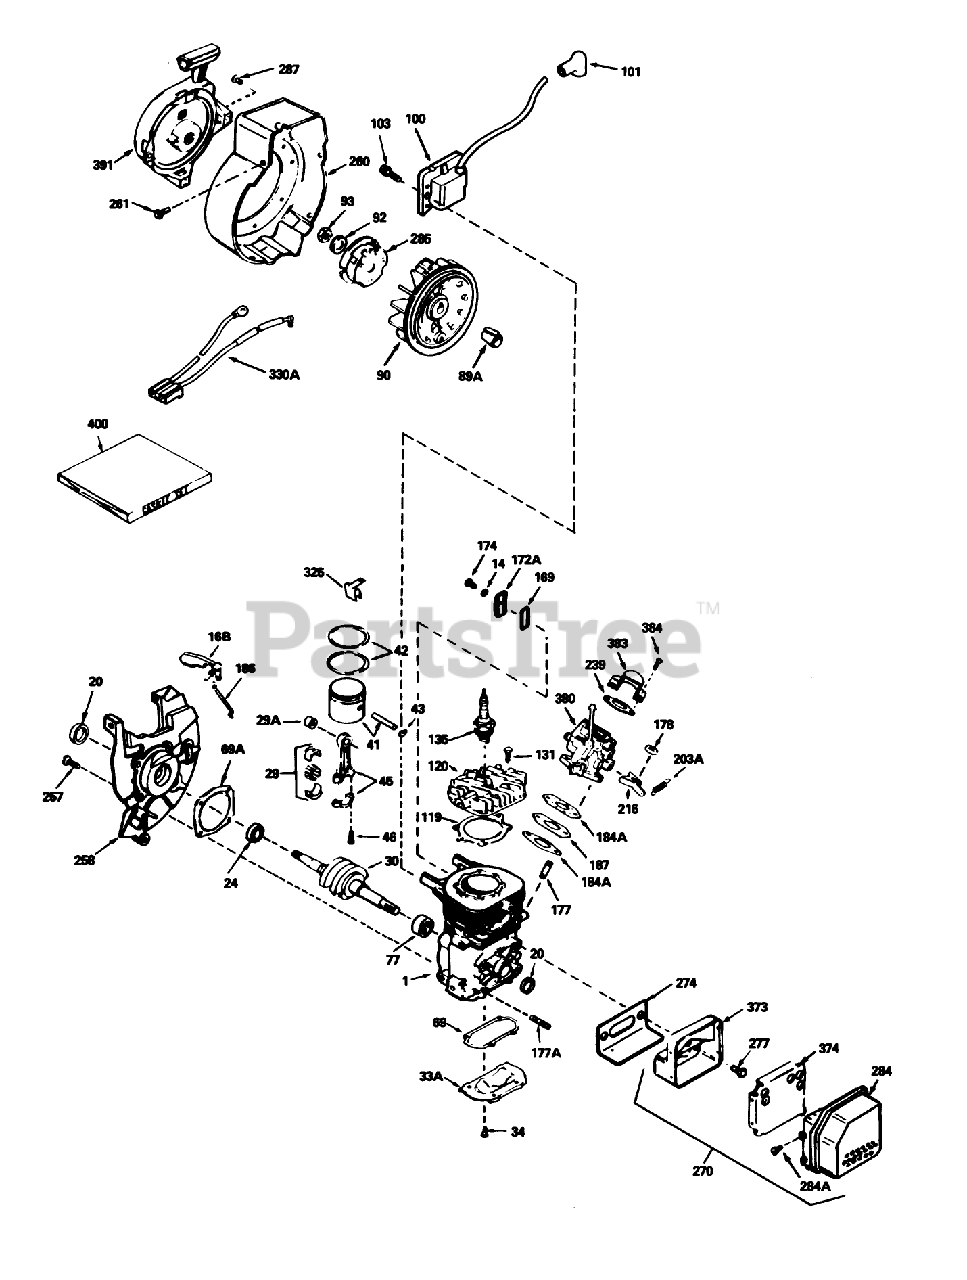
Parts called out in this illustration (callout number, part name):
1	Block Ass-y-Cylinder (Order short block if replacement is required)
14	Washer
16B	Vane-Air
20	Seal-Oil
24	Bearing-Ball
29	Needle Bearing and Liner Set (37 Needles)
29A	Bearing-Cartridge
30	Crankshaft
33A	Plate-Cover
34	Screw (T-25, 10-24 x 1/2)
41	Piston (Incl. Ref. #43)
42	Ring Set
43	Ring-Retaning
45	Rod Assy.-Connecting (Incl. Ref. #3, 3A 3B)
46	Bolt-Rod, Connecting
69	Gasket-Plate, Cover
69A	Gasket-Cover, Cylinder
77	Bearing-Cartridge
89A	Blade (20 inch)
90	CARB BODY S
92	Washer-Belleville
93	Nut-Flywheel
100	Solid State
101	Cover-Spark Plug
103	Screw
119	Gasket-Head, Cylinder
120	Head-Cylinder
131	Screw (T-30, 1/4-20 x 3/4)
135	Spark Plug-Resistor (R C J 8Y)
169	Cover-Compression, Release
172A	Comp. Release Cover
174	Screw (T-25, 10-24 x 1/2)
177	Stud-Carburetor
178	Nut and Lock Washer (1/4-28)
184A	Gasket-Carburetor
186	Link-Governor
187	Spacer
203A	Spring-Governor
216	Lever-Adjusting, Rpm
239	2060A77 WIZARD ROTA
257	Screw (T-30, 1/4-20 x 5/8)
258	Base Ass-y-Blower Housing (Incl Ref. #20)
260	Housing-Blower
261	Screw (1/4-20 x 1/2)
270	Muffler Assembly (Incl. Ref. #53-57)
274	Gasket-Exhaust
277	Screw (T-30, 1/4-20 x 5/8)
284	Cover Muffler
284A	Screw
285	Cup-Starter
287	Rivet-Pop
325	Clip-Wire
330A	Harness-Wire
373	Base-Muffler
374	Baffle-Muffler
380	Carburetor (Incl. Ref. #184A)
383	Baffle-Carburetor
384	Screw
391	Starter-Rewind
400	Gasket Set
